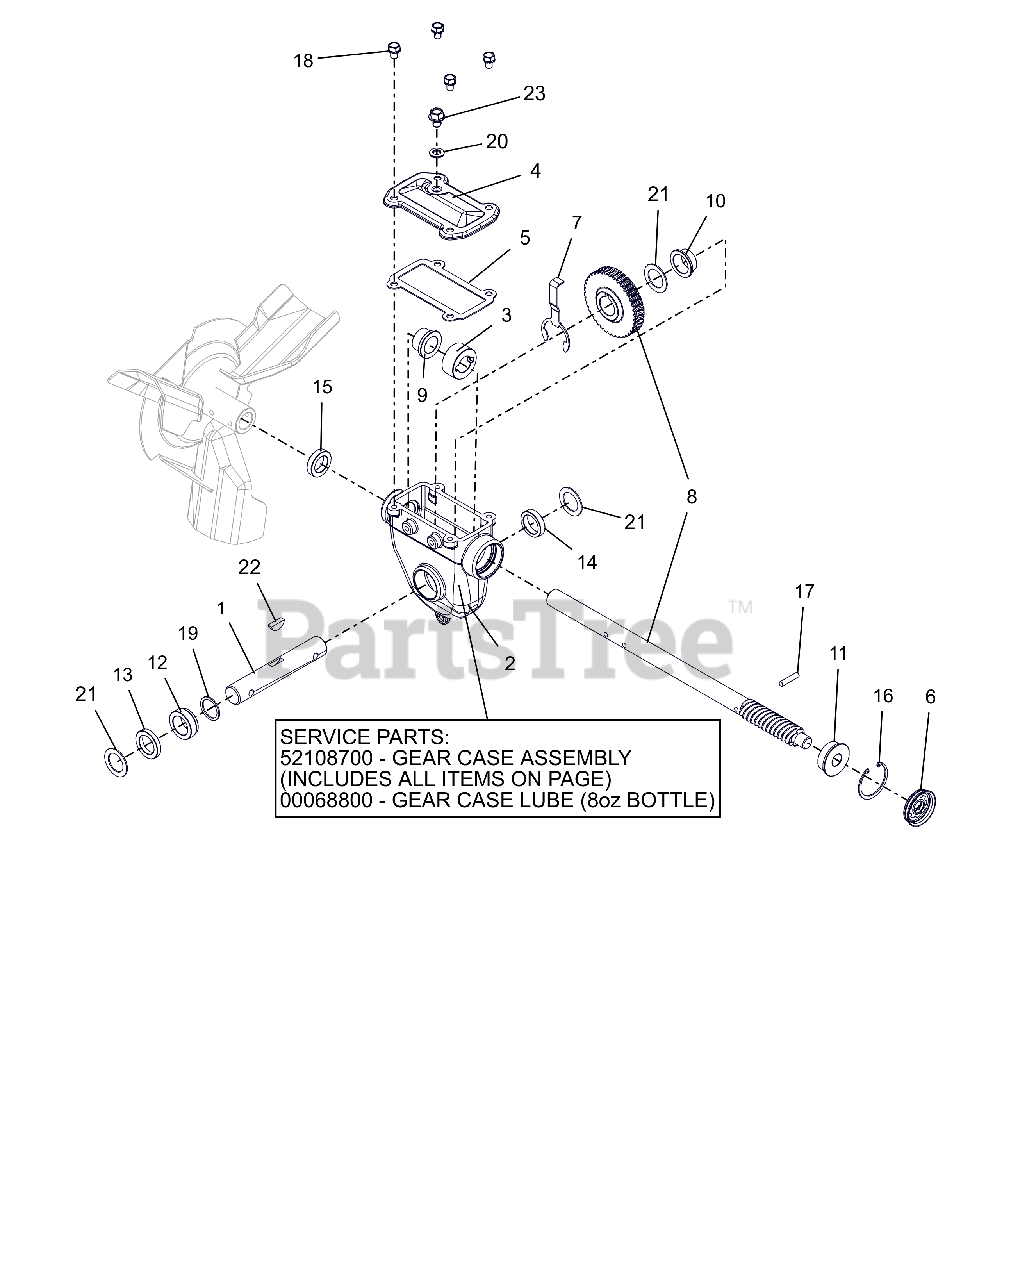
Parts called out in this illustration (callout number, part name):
1	RAKE SHAFT, SHORT-COMMON
2	GEARCASE, LARGE MACHINED
2	ARIENS L3 LUBE, 8 OZ BOTTLE
2	KIT, SERVICE - DLX GEAR CASE
3	THRUST COLLAR, .875"ID SLIPFIT
4	COVER, TOP - LARGE IRON
5	GASKET, TOP - LARGE GEARCASE
6	COVER, GEAR CASE 1.75"
7	BUSHING RETAINER, LARGE
8	KIT, SERVICE-WORM SHAFT & GEAR
9	BSHG-FLG .879X1.128X.75X1.45
10	BSHG-FLG 1.006X1.128X.555X1.45
11	BSHG-FLG .628X1.503X.58X1.725
12	BSHG-FLG LARGE, RIGHT
13	SEAL-OIL .999X1.500X.250 TBC29
14	SEAL-OIL .999X1.375X.312 TBC29
15	SEAL-OIL .873X1.375X.312 TBC29
16	RG-RTNG-INT 1.750X.062
17	PIN-STR .250X1.12 6150
18	BLT, SEMS .31-18X.50 G5 ZCC
19	WSHR, FLT 1.010X1.250X.068 ZCC
20	WSHR-BND-SEAL .38X.75X.11 GALV
21	WSHR, FLT 1.010X1.505X.062 ZCC
22	KEY-WDRF .25X.875 HRD #A
23	SCR,TAP .38-15X.50 HWH ROLOK
